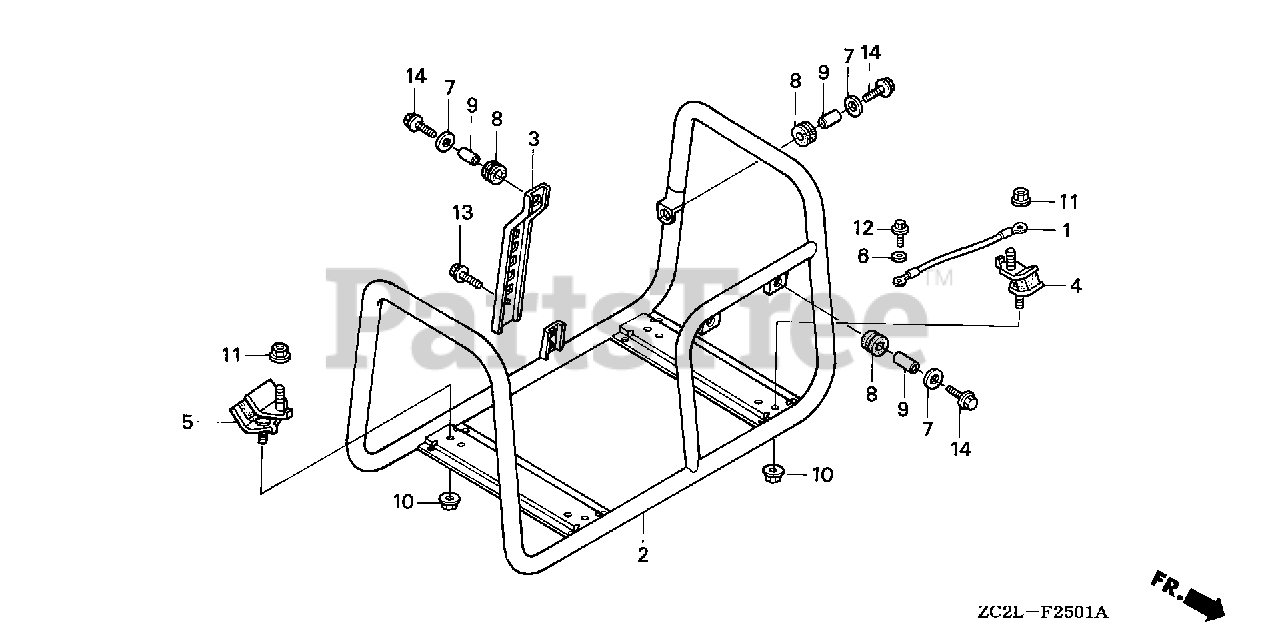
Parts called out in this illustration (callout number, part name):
1	CABLE, GROUND
2	FRAME *NH105* (MAT BLACK) (NOT AVAILABLE)
3	CHANNEL, FR. *NH105* (MAT BLACK)
4	RUBBER (LOWER)
5	RUBBER (LOWER)
6	WASHER, LOCK (6MM)
8	RUBBER, CONTROL BOX
9	COLLAR, CONTROL BOX
10	NUT, FLANGE (8MM)
11	NUT, FLANGE (10MM)
12	BOLT, FLANGE (6X10)
13	BOLT, FLANGE (6X12)
14	BOLT-WASHER (6X20)
